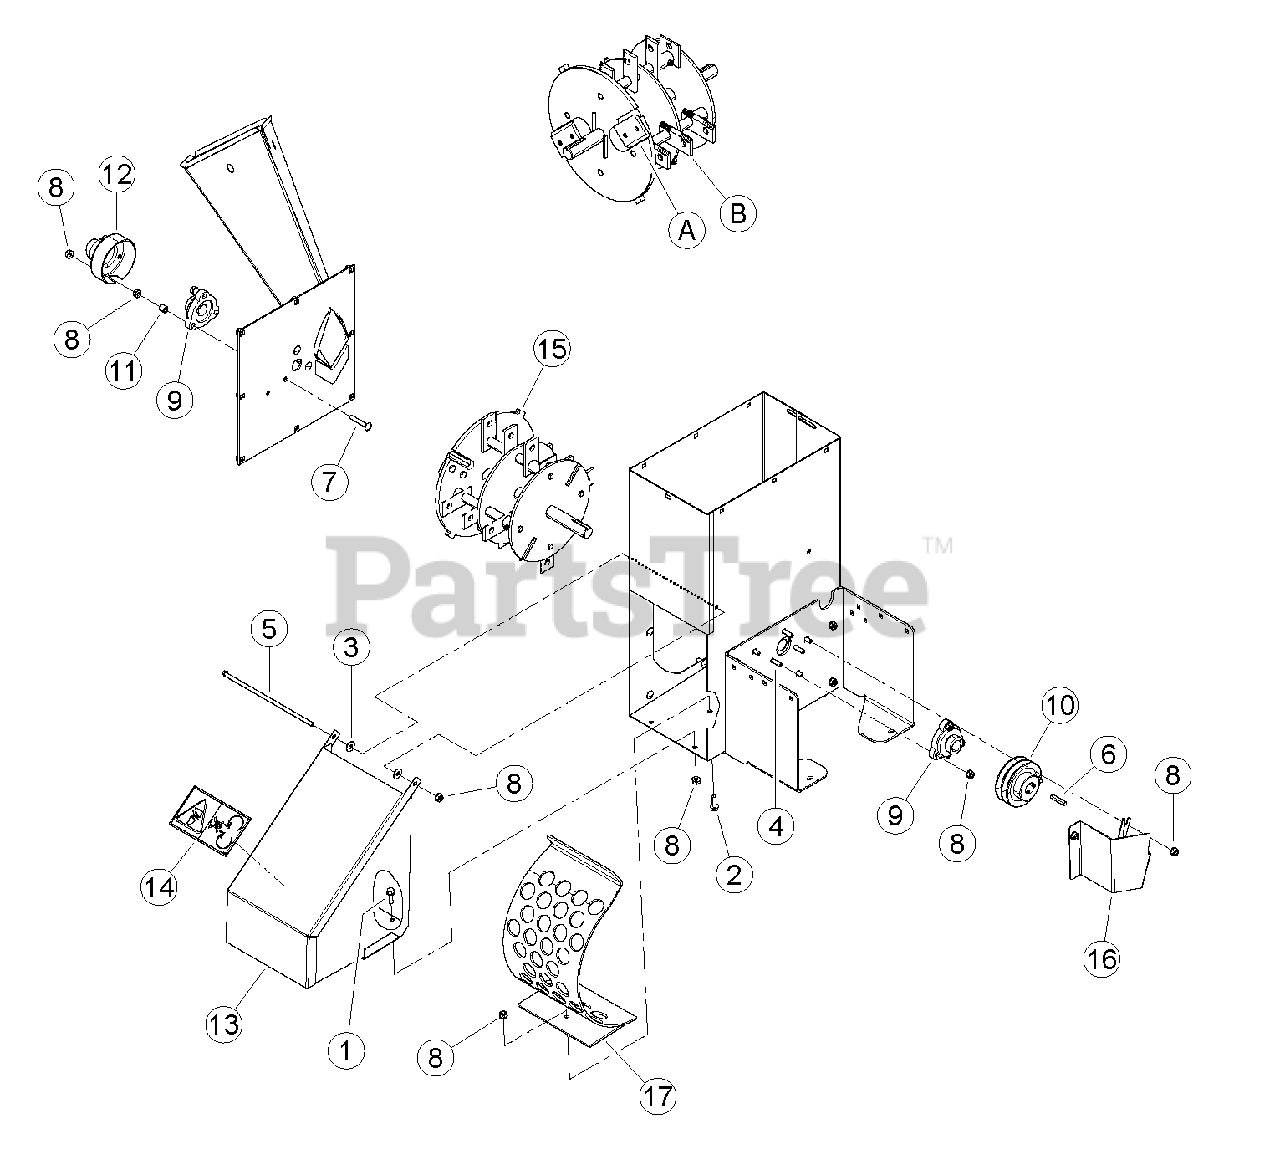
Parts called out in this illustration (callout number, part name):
1	BOLT, 5/16 X 3/4 FLANGE NC
2	BOLT, 5/16 X 1 FLANGE NC
3	WASHER, 5/16 FLAT ZP
4	BOLT, 5/16 X 1-1/4 CRG GR5 ZP
5	BOLT, 5/16 X 10 HEX GR5 NC ZP
6	KEY, 1/4 SQUARE X 1-1/2 LONG PLAIN
7	BOLT, 5/16 X 2 CRG GR5 NC ZP
8	NUT, 5/16-18 NYLOCK-FLANGE
9	BEARING, 1" FLUSHMOUNT CAST W/COLLAR
10	PULLEY, 4 X 1 2A GROOVE
11	SPACER, .54OD X .50" LG
12	CAP, ROTOR SHAFT END CAP
13	ASSEMBLY, WIDE EUROPEAN DISCHARGE
14	DECAL, BLADE DANGER ISO
15	ASSEMBLY, BALANCED ROTOR
16	SHIELD, LOWER
17	WELDMENT, WIDE COARSE TAPERED
A	KIT, TOOL STEEL BLADE
B	KIT, 3" WIDE SHREDDER KNIVES
